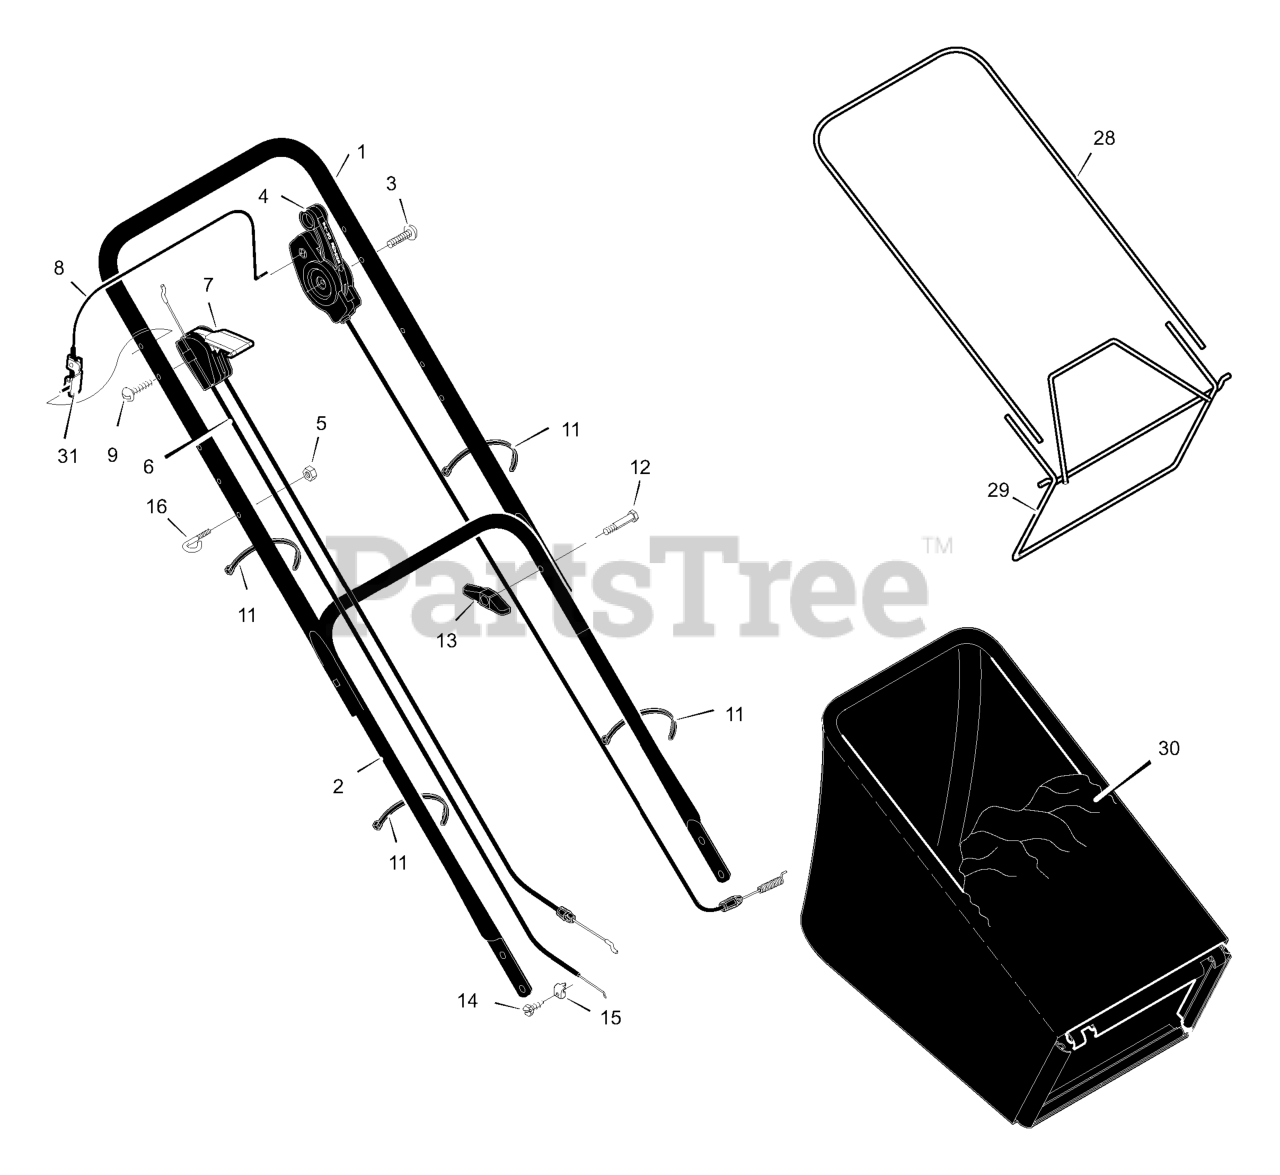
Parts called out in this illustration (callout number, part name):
1	Engine
1	Handle, Upper (Black)
2	Handle, Lower (Black)
4	Control, Drive
5	Locknut
6	Cable, Stop
7	Throttle Control
8	Engine Stop Lever
11	Fastener, Cable
13	Knob
16	GUIDE, ROPE
17	Cap
18	Nut
20	Cover, Ignition
21	Switch Ignition & Key
22	Charger, Battery
23	Harness, Wiring
24	Battery
25	Case, Battery
26	Bracket, Battery
27	Key, Ignition
28	Frame, Top
29	Frame Assembly
30	Bag, Cloth
31	Bracket, Stop Lever
